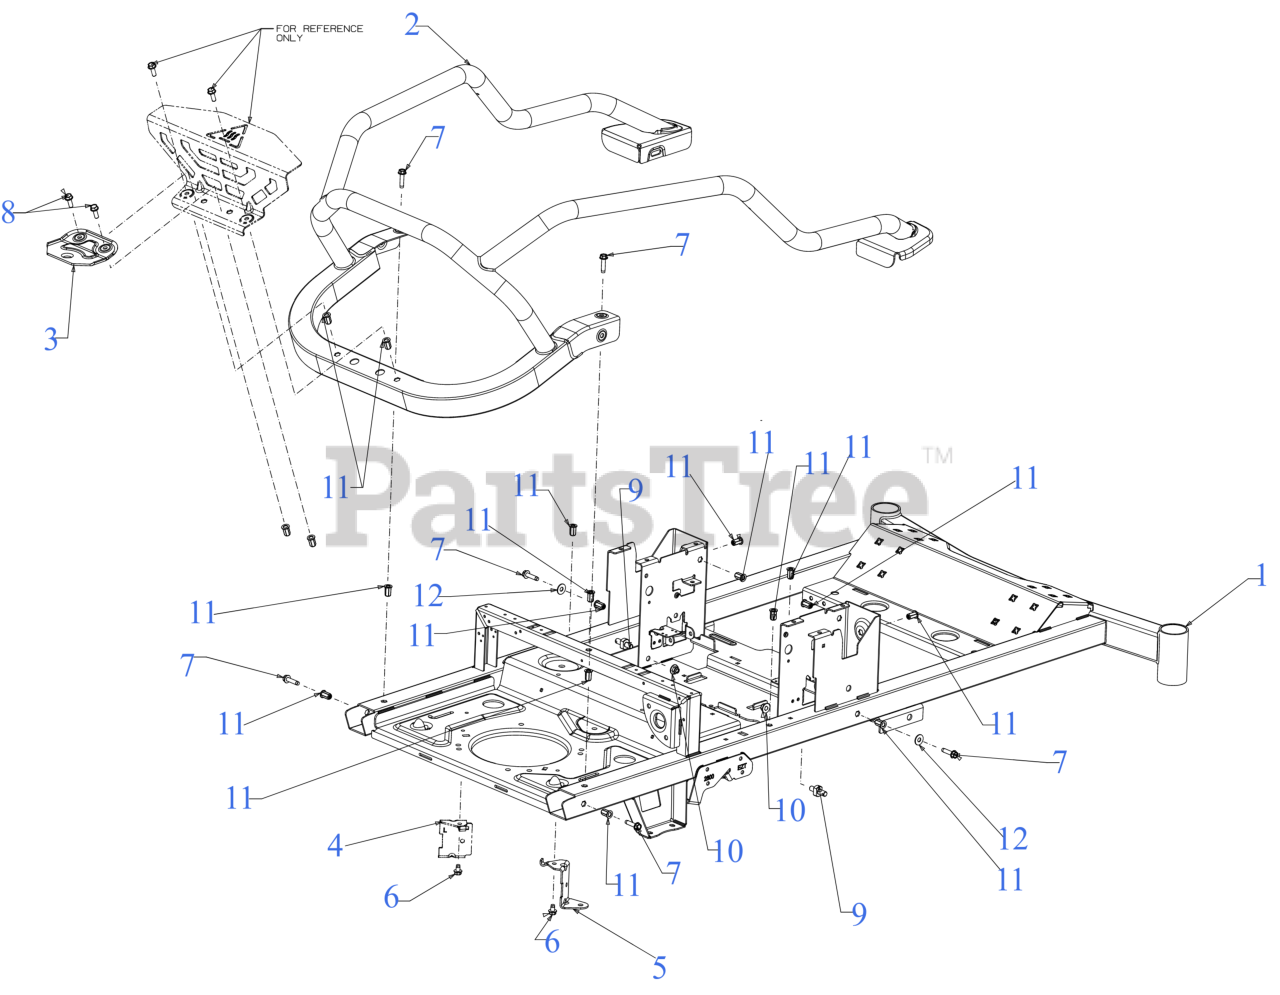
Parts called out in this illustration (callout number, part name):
1	FRAME
2	UPPER FRAME
3	HITCH PLATE
4	TRANSMISSON MOUNT SUPPORT (LH)
5	TRANSMISSON MOUNT SUPPORT (RH)
6	SCREW 5/16-18 x .500
7	SCREW 5/16-18 x 1.25
8	SCREW 5/16-18 x .875 GR5
9	SHOULDER STUD
11	NUT RIVET 5/16-18
12	FLAT WASHER
